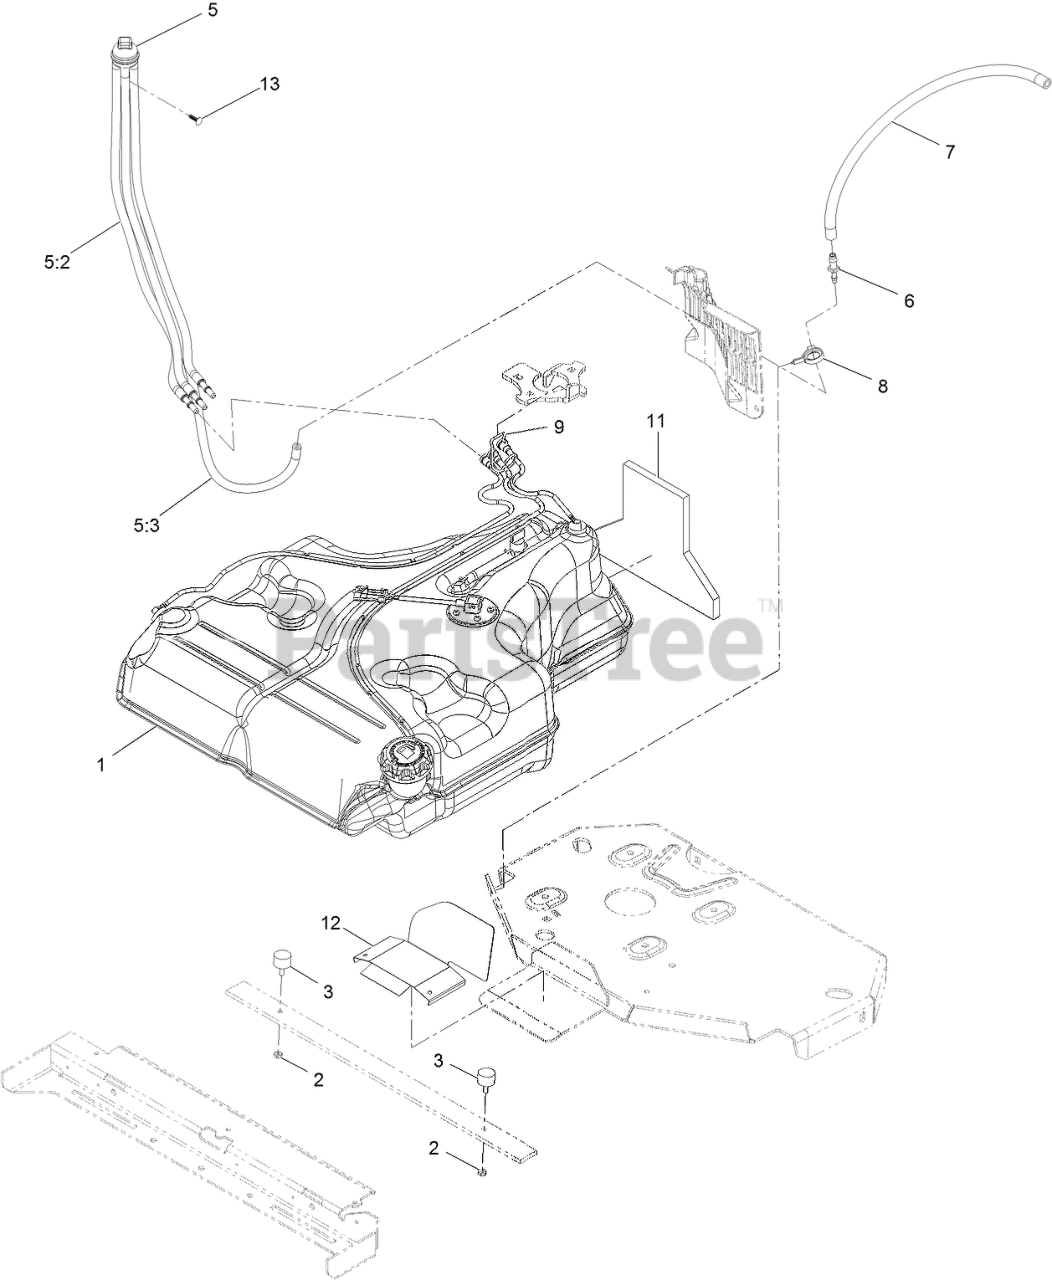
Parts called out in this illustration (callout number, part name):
1	FUEL TANK ASM
2	NUT-JAM
5	FUEL MANIFOLD VENT ASM
5:2	HOSE-FUEL
5:3	HOSE-FUEL
6	FITTING-STRAIGHT
7	HOSE-FUEL
8	CLAMP-HOSE
9	RETAINER-LINE, VAPOR
11	INSULATION-FOAM, FUEL TAN
12	GUARD-EXHAUST
13	PLUG-PLASTIC
